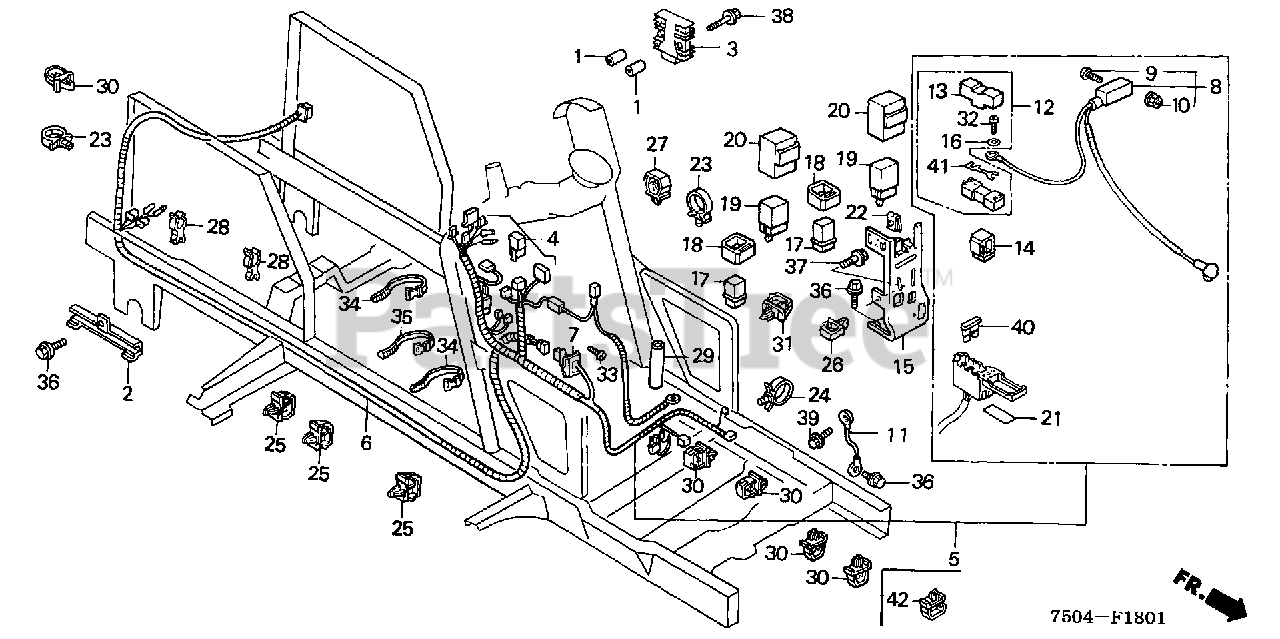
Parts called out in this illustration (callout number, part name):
1	COLLAR, FAN
2	PROTECTOR, WIRE
3	RECTIFIER ASSY., REGULATOR
4	DIODE ASSY.
5	WIRE HARNESS, MAIN
6	SUB-WIRE HARNESS ASSY., RR.
7	HOLDER, CONNECTOR
8	CABLE ASSY., STARTER
9	BOLT, BATTERY TERMINAL (SUMITOMO)
9	BOLT, BATTERY TERMINAL
10	NUT, BATTERY TERMINAL (SUMITOMO)
11	CABLE ASSY., BONDING
12	BOX, MAIN FUSE (NOT AVAILABLE)
13	COVER (NOT AVAILABLE)
14	SUSPENSION, MAIN FUSE
15	BRACKET, ELECTRIC PARTS
16	WASHER, PLAIN (3X10)
17	RELAY, CONTROL
18	SUSPENSION, CONTROL RELAY
19	RELAY, STARTER
20	SUSPENSION, STARTER RELAY (OMRON)
20	SUSPENSION, STARTER RELAY (MITSUBA)
21	LABEL, FUSE
22	NUT, CLIP (6MM)
23	CLIP, WIRE HARNESS
24	CLIP, HARNESS
25	CLIP, HARNESS (15MM) (BLUE)
26	CLIP, WIRE HARNESS (13MM) (GRAY)
27	CLIP, HARNESS (10MM)
28	CLAMP, PIPE (5-13)
29	TUBE, CORD (22MM)
30	CLIP, WIRE HARNESS
31	CLIP, HARNESS (7MM)
32	SCREW, PAN (3X8)
33	SCREW, PAN (6X8)
34	BAND B2, CABLE HARNESS
35	BAND B3, CABLE HARNESS
36	BOLT, FLANGE (6X10)
37	BOLT, FLANGE (6X12)
38	BOLT, FLANGE (6X40)
39	BOLT, FLANGE (8X12)
40	FUSE, BLADE (5A)
41	FUSE F (20A)
